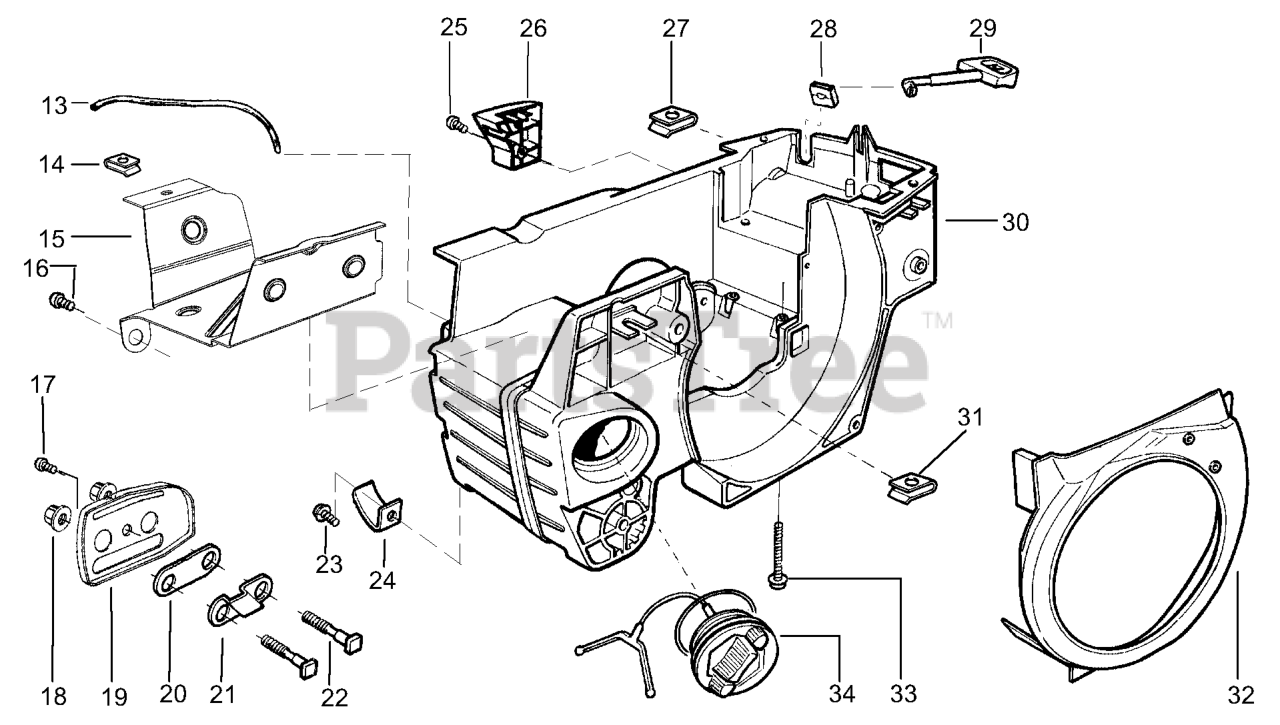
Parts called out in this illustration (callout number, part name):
13	TUBE
15	HEATSHIELD, LOWER
16	SCREW-10-14 X 1/2 PLASTITE
17	SCREW
20	OIL TANK GASKET
21	PLATE,BAR MOUNT
22	BAR BOLT 36/41
24	CHAIN CATCHER 36/41
26	LIMITER COVER
28	CHOKE GUIDE 36/41
29	CHOKE 36/41
30	CRANKCASE ASSY
32	AIR CONDUCTOR 36/41
33	SCREW M5-0.8X35M TAP
